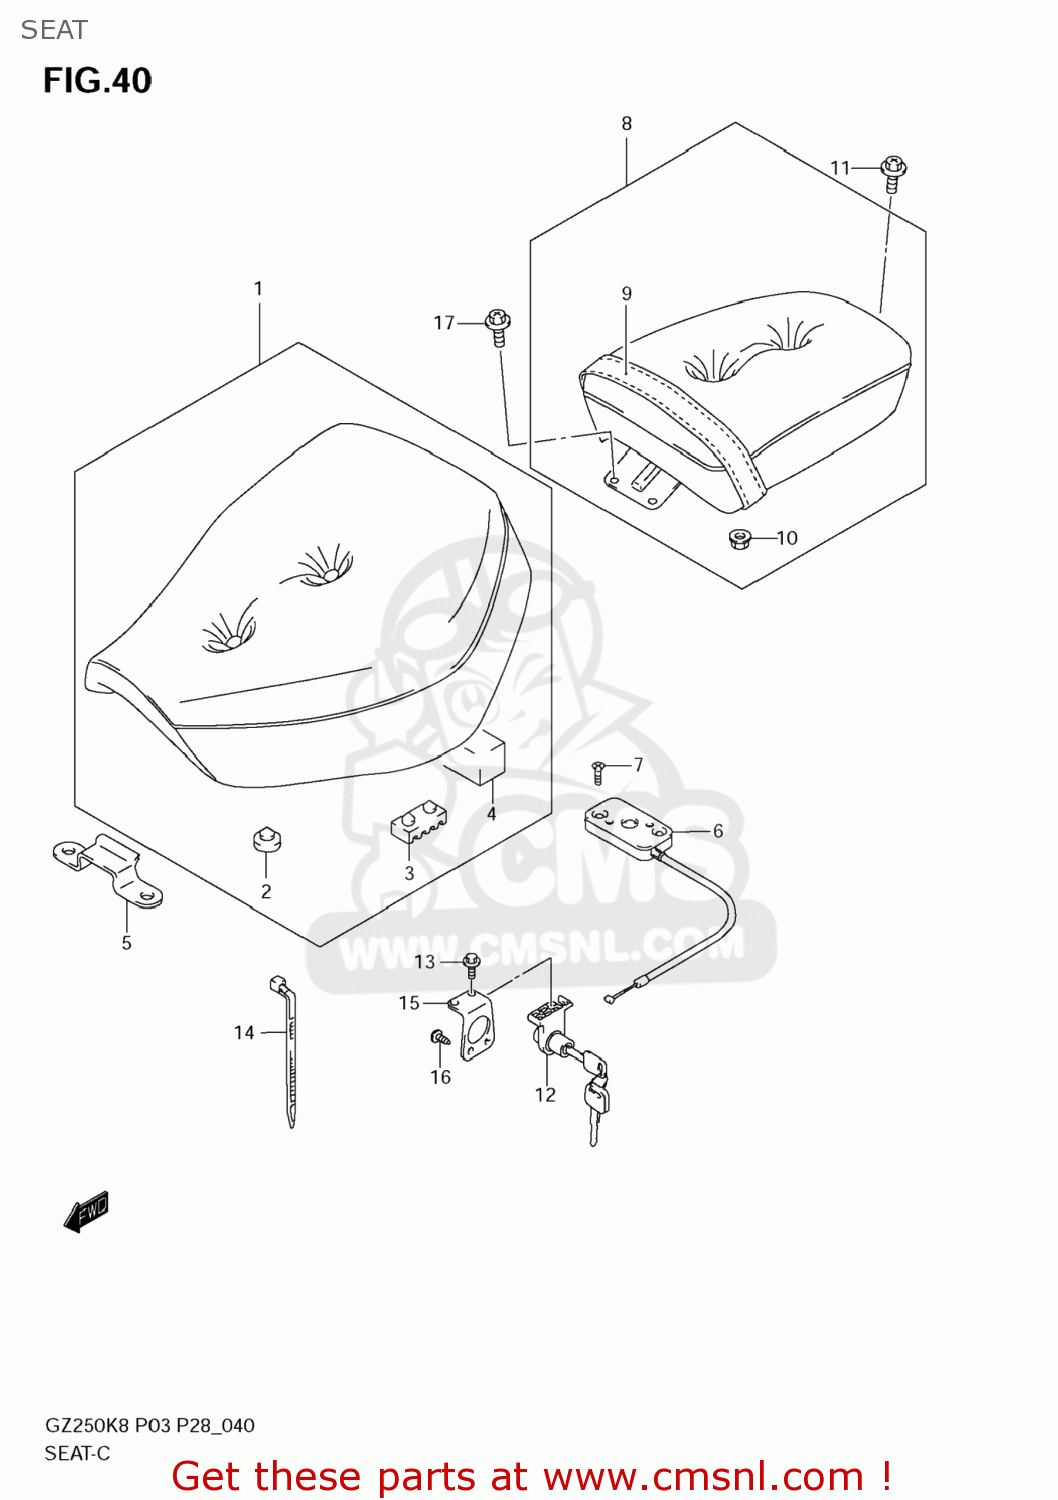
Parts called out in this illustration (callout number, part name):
1	SEAT ASSY
2	CUSHION,FRONT
3	CUSHION,RR
4	CUSHION, TOOL
5	PLATE,FR SEAT HOOK
6	BRACKET,SEAT SUPPORT
7	SCREW
8	SEAT ASSY PILLI
9	BAND, SEAT
10	NUT
11	BOLT(8X16)
12	LOCK SET,SEAT
13	BOLT
14	CLAMP(L:220)
15	BRACKET,SEAT LOCK
16	SCREW
17	BOLT(6X12)
